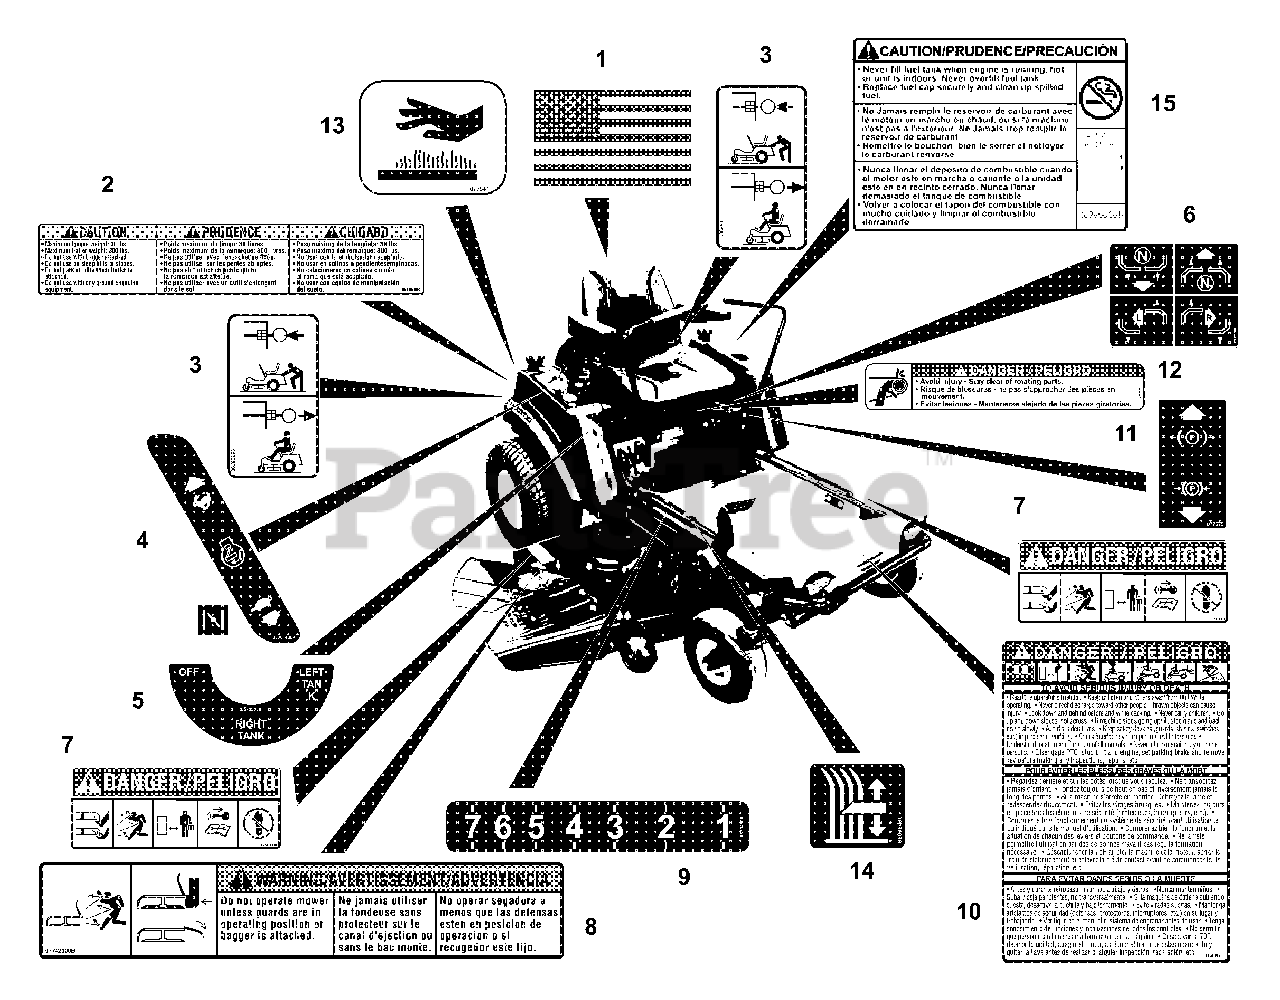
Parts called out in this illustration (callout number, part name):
1	DECAL, AMERICAN FLAG
2	DECAL, TRAILER HITCH
3	DECAL, TRANSMISSION DISCONNECT
4	DECAL, SPEED CONTROL
5	DECAL, FUEL VALVE
6	DECAL, INSTRUCTIONAL-STEERING
7	DECAL, MOWER PAN DANGER
8	DECAL, WARNING
9	DECAL CUT HEIGHT
10	DECAL, DANGER BILINGUAL
11	DECAL, PARKING BRAKE LEVER
12	DECAL- DANGER
13	DECAL, HOT SURFACE
14	DECAL-CUT HEIGHT
15	DECAL,FUEL WARNING
